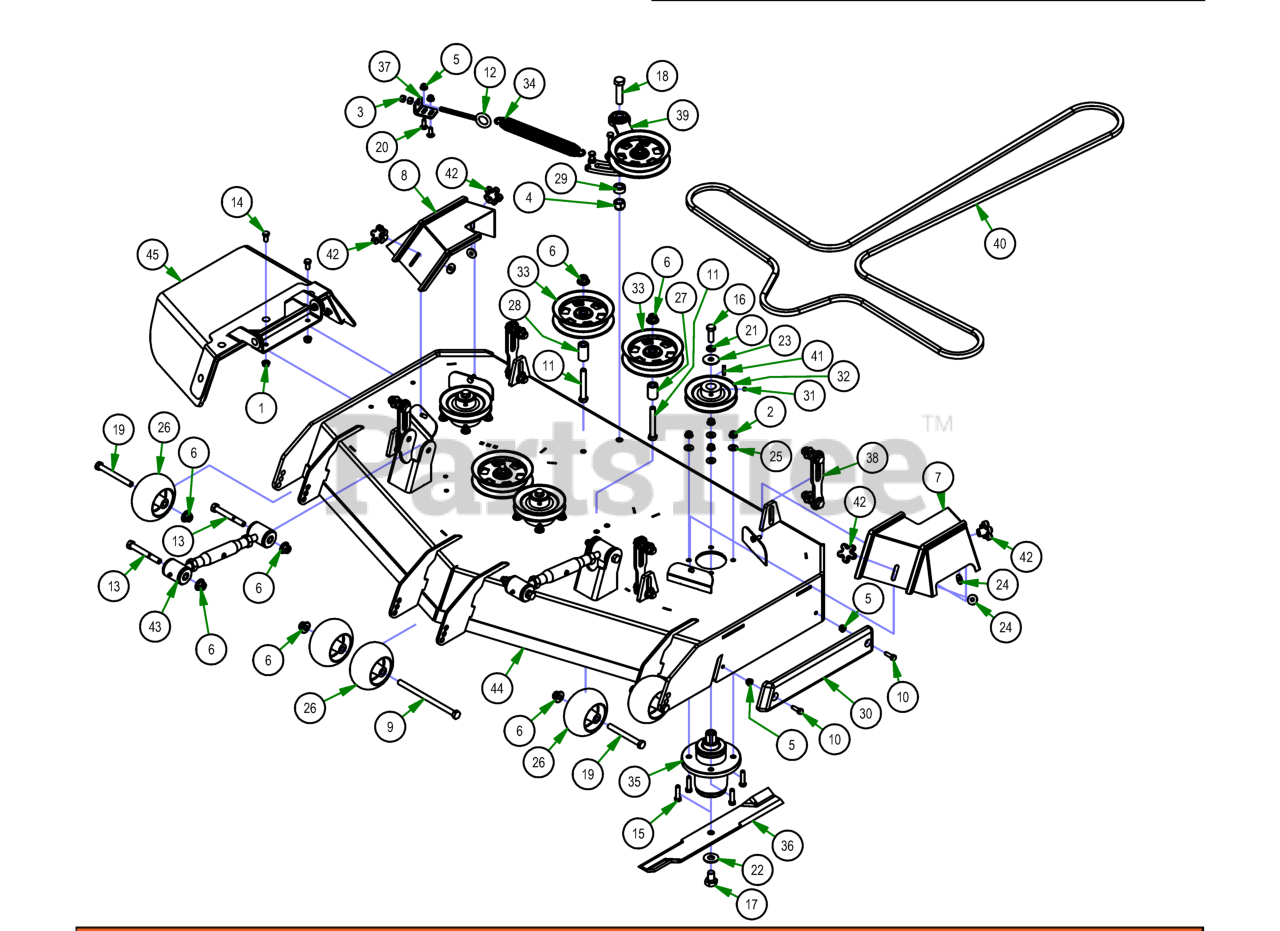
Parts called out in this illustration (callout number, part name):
1	3/8" Flange Nut
2	3/8-16 NYLON INSERT FLANGE LOCKNUT (GR.F) ZINC
3	3/8" Hex Nut
4	5/8 Std NC Nylock Nut
5	5/16" Nylon Flange Nut
6	1/2-13 NYLON INSERT FLANGE LOCKNUT ZINC
7	2019 54" Left Outlaw Gen2 Pulley Cover
8	2019 54" Right Outlaw Gen2 Pulley Cover
9	1/2-13 x 8 Hex Bolt Grade 5
10	5/16-18 x 1 GR 5 Hex Bolt Zinc
11	1/2 x 3 1/2 Flange Bolt Grade 8
12	4" 3/8-16 Eye Bolt
13	1/2" x 4" Bolt (Grade 8)
14	3/8" x 3/4" Hex Bolt
15	3/8-16 X 1-1/2 HEX CAP SCREW (GR.5) ZINC
16	1/2"-20 x 1 1/2 - Grade 5 Fine Thread Bolt
17	5/8" x 1 1/2" Grade 8 Hex Bolt (Fine)
18	5/8" x 2 1/2" Grade 5 Hex Bolt (Coarse)
19	1/2" x 4 1/2" Bolt
20	5/16" x 7/8" Carriage Bolt
21	1/2" Lock Washer
22	5/8'' Flat Washer
23	1/2" Belleville Washer
24	.360 ID Plastic Washer-Black
25	5/16 USS FLAT WASHER (7/8 OD) ZINC
26	2019 Deck Wheel
27	.502 ID X .750 OD X 1.500 Long Spacer
28	1 3/4" Pulley Spacer
29	5/8" x 1/" Collar W/One Set Screw
30	REVISED TRIM BUMPER_20180226
31	5/16 Set Screw
32	5.25" Deck Spindle Pulley
33	5-3/4 Idler Pulley
34	2019 Outlaw Gen2 Deck Spring
35	OUTLAW SPINDLE ASSEMBLY
36	54" Fusion Blade for ZT/Mav/Outlaw/Revolt
37	2019 Deck Eye Bolt Tab
38	Deck Hangar Assembly
39	2019 Rebel Rogue Deck Idler
40	B165 Belt-60 54" deck Outlaw
41	1/4" x 1" Key
42	5/16" Knob
43	Turnbuckle
44	2019 Sloped 54" Deck
45	2019 Outlaw Gen2 Chute Assembly
